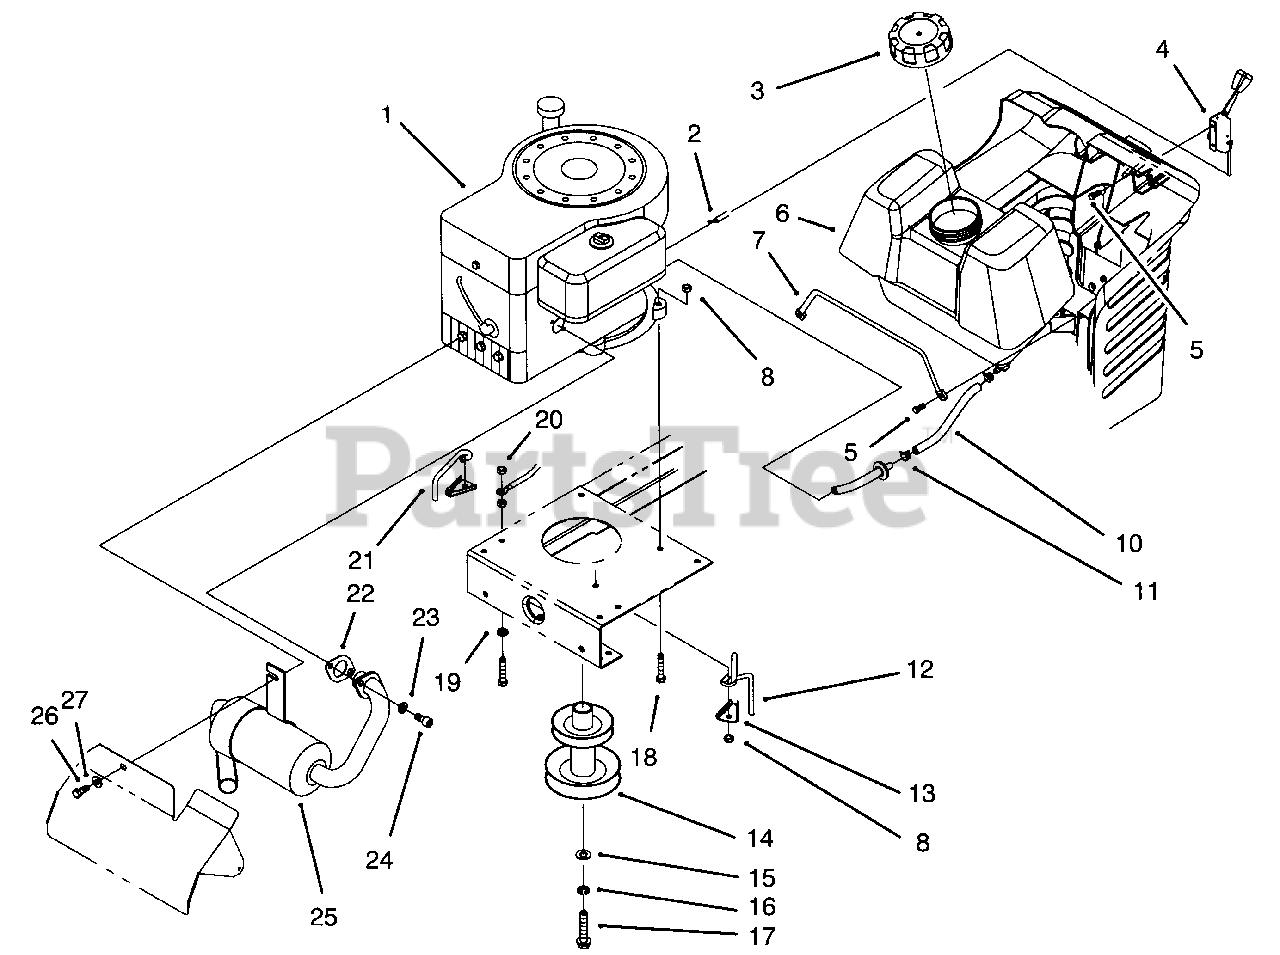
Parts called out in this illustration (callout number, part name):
1	Engine-12 H.P.
2	Cable-Throttle
4	Control-Throttle
5	Screw-Plastite
6	Tank-Gas
7	Rod-Gas Tank
8	Nut-Lock
10	Line-Fuel
11	Clamp-Hose
12	Guide-Belt L.H.
13	Anchor-Belt Guide
14	Pulley-Engine
15	Washer-Flat
16	Washer-Lock
17	Bolt-Blade
18	Screw-Hex Hd. Cap
19	Washer-Ext. Tooth Lock
20	Nut-Keps
21	Guide-Belt R.H.
22	Gasket-Muffler
23	Washer-Lock
24	Screw-Hex Soc. Hd.
26	Screw-Hex Hd. Cap
27	Washer-Lock
